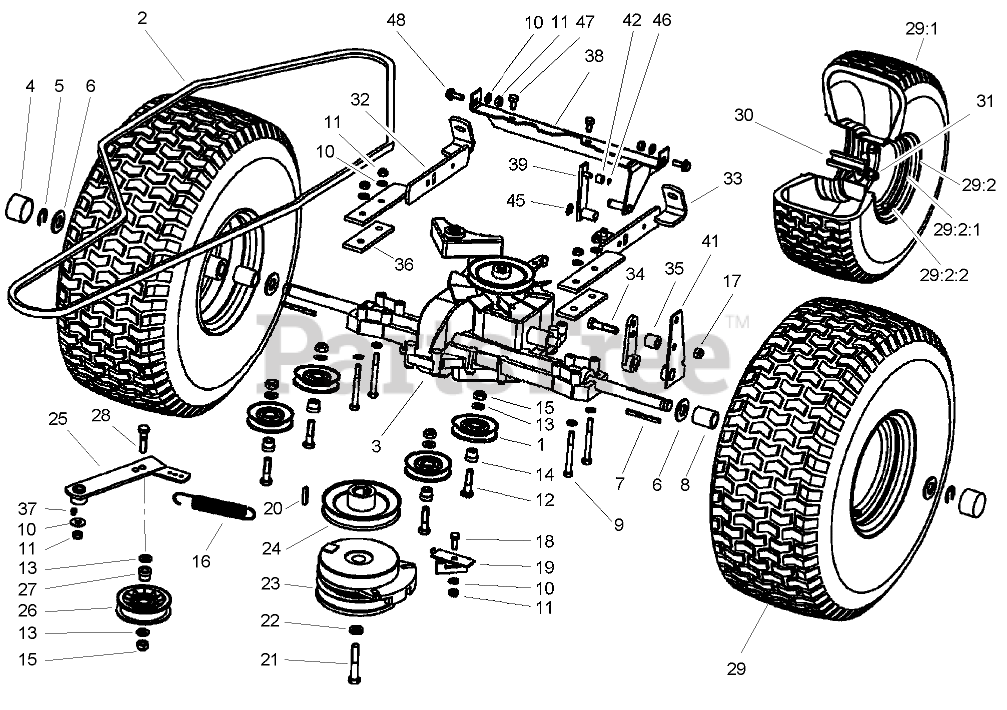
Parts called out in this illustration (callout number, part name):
1	PULLEY-IDLER
2	V-BELT-TRACTION
3	TRANSMISSION
4	CAP-HUB
5	CLIP-SPRING
6	WASHER
7	KEY-SQUARE
8	SPACER-AXLE
9	SCREW-HH
10	WASHER-PLAIN
11	NUT-LOCK, NI
12	SCREW-HH
13	WASHER-FLAT
14	BUSHING-IDLER
15	NUT-LOCK, NI
16	SPRING
17	NUT-LOCK, NI
18	SCREW-HH
19	RETAINER
20	KEY-SQUARE
21	SCREW-HH
22	WASHER-SPRING, BELLEVILLE
23	CLUTCH-ELECTRIC
24	PULLEY-ENGINE
25	ARM-IDLER
26	PULLEY-IDLER
27	BUSHING-IDLER
28	SCREW-HH
29	TIRE AND WHEEL ASM
29:2	WHEEL ASM
29:2:1	Rim
29:2:2	Valve-Tire
30	HUB-WHEEL
31	NUT-WHEEL
32	Bracket-Right
33	Bracket-Left
34	SCREW-HH
35	SLEEVE
36	Plate-Reinforcing
37	FITTING-GREASE
38	Bar ASM
39	Arm-Switch
42	Roller
45	Stirrup
46	STIRRUP
47	SCREW-THREAD FORMING
48	SCREW-HEX
